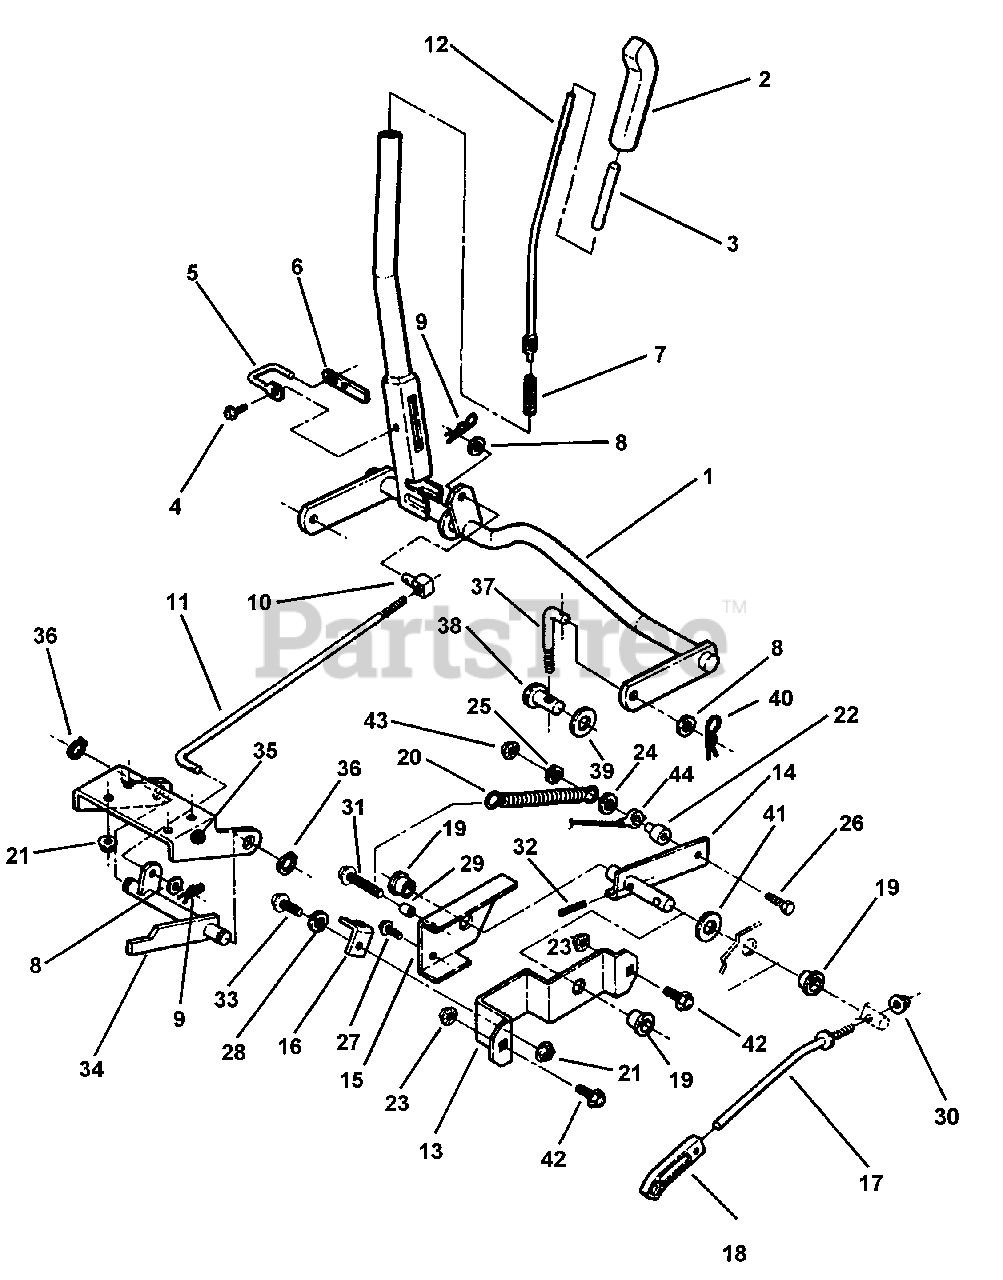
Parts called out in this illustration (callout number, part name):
1	WELDMENT, Lift Handle Cross-Rod
2	KNOB, Lift Handle
3	BUTTON, Lift Handle Release
4	SCREW, 1/4-20 x 5/8 Hex Washer Self-Tap
5	PIVOT, Latch Detent
6	DETENT, Lift Lever
8	WASHER, 3/8" Flat
9	COTTER-PIN, 1/16" x 1.42" Self-Locking
10	SWIVEL, Brake Link
11	ROD, Timing
12	ROD, Lift Lever
13	BRACKET, Blade Engagement
14	WELDMENT, Engagement Arm
15	SUPPORT, Shaft
16	FORK, Cable Anchor
17	LEVER, Blade Engagement
18	GRIP, Blade Engagement Lever
19	BUSHING, Nylon
20	SPRING
21	NUT, 5/16-18 Hex Flange Lock, Grade 5
22	SPACER, Cable Anchor
23	NUT, 1/4-20 Hex Flange Lock, Grade 5
24	WASHER, 3/8" Flat
25	WASHER, 1/4" I.D. x 5/8" O.D. x 1/16" Thick Flat
26	SCREW, 1/4-20 x 1-1/2" Hex Head Cap
27	SCREW, 1/4-20 x 3/8" Hex Washer Self-Tap
28	SPACER
29	SPACER
30	NUT, 3/8-16 Hex Nyloc
31	SCREW, 1/4-20 x 1-1/4" Hex Washer Self-Tap
32	PIN, 1/4 x 1" Roll
33	BOLT, 5/16-18 x 5/8" Hex Flange Lock
34	WELDMENT, Front Lift Arm
35	BRACKET, Front Lift Arm
36	RING, 3/4" External Retaining
37	LINK, Leveling
38	SWIVEL, Deck Support
39	WASHER, 1/2" Flat
40	PIN, 3/32 x 1-1/2" Hair
41	WASHER, 5/8" Flat
42	BOLT, 1/4-20 x 3/4" Short Neck Carriage, Grade 5
43	NUT, 1/4-20 Hex Center Lock
44	CABLE, Blade Engagement
